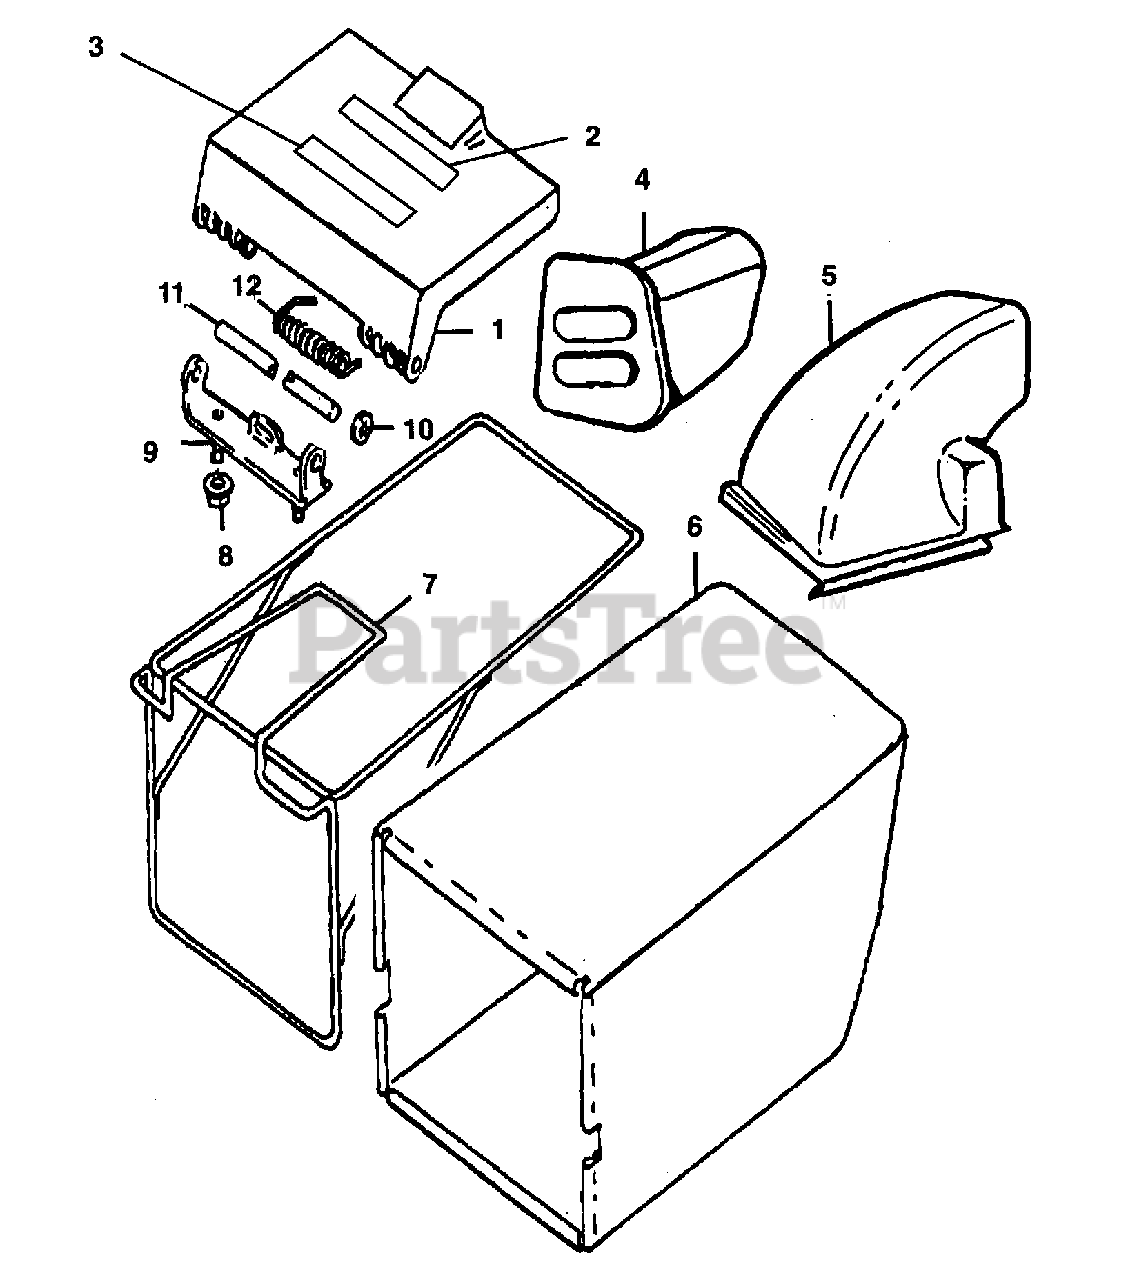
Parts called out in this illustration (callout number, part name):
1	COVER WITH LABEL
4	MULCH PLUG
5	SIDE DISCHARGE CHUTE
6	GRASS BAG
7	FRAME, GRASS BAG
8	LOCK NUT,COVER
9	HINGE, COVER
10	RETAINER, COVER
11	ROD, COVER
12	SPRING, COVER LH.
